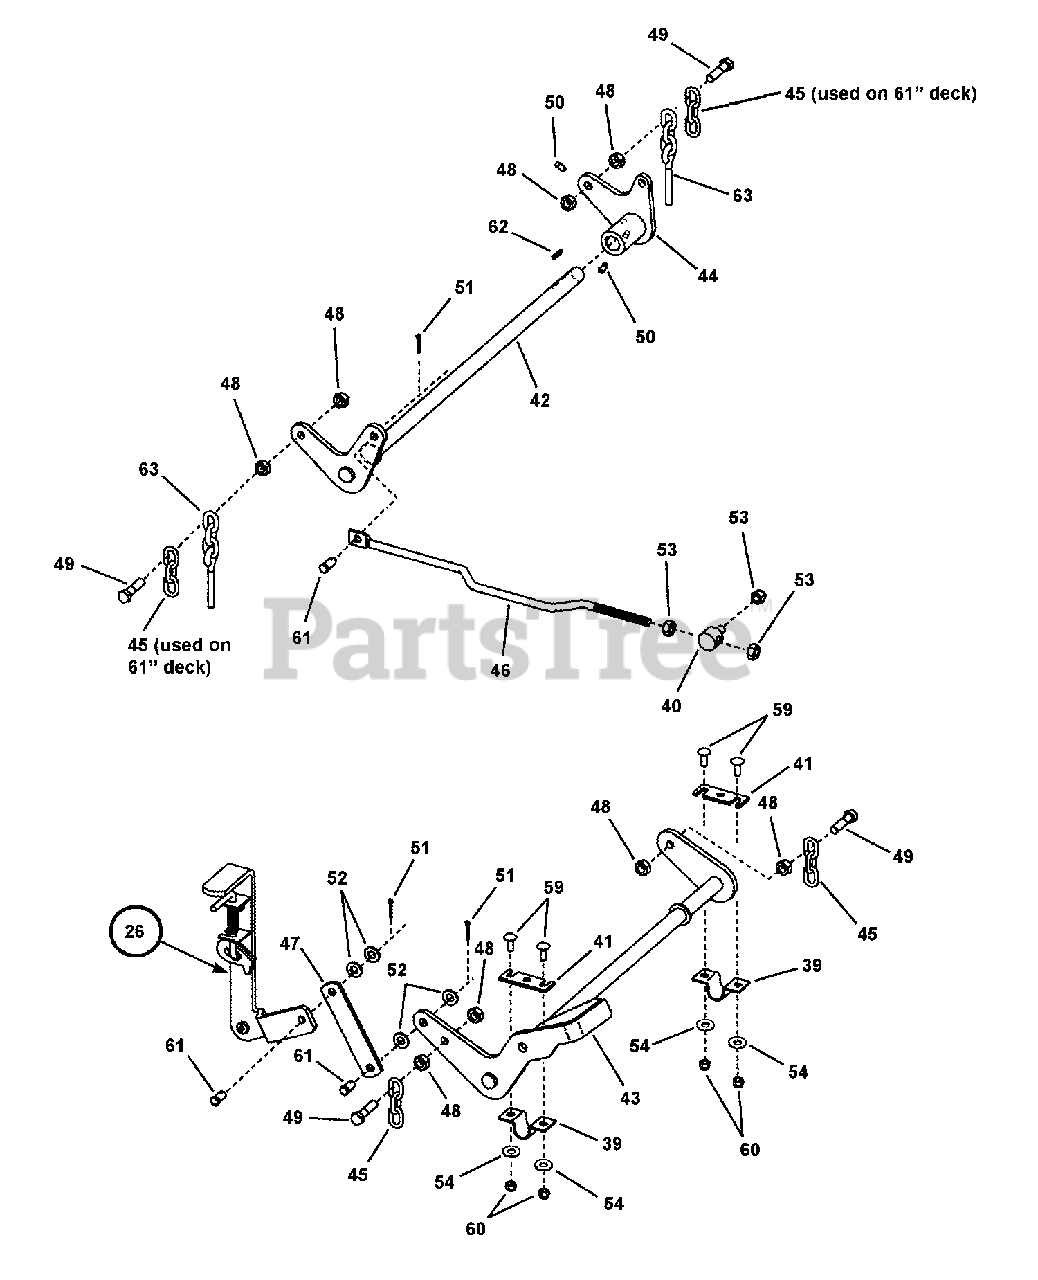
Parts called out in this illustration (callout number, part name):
26	ASSY, Deck Lift Handle
39	BRACKET, Deck Support
40	SWIVEL, Timing Rod (1/2-13 External Thread)
41	SHIM PLATE
42	WELDMENT, Rear Lift
43	WELDMENT, Front Deck Lift
44	WELDMENT, Bellcrank Lift
45	CHAIN, 3 Links
46	ROD, Timing (1/2-13 Thread)
47	LINK, Front
48	NUT, 1/2-13 Hex Flange GR5
49	SCREW, 1/2-13 x 2" Hex Head Cap, GR5
50	SET SCREW, 5/16-18 Square Head Cup Point
51	PIN, 5/32 x 1" Cotter
52	WASHER, .531 I.D. Flat
53	NUT, 1/2-13 HEX SIDE LOCK
54	WASHER, 5/16" Flat
59	BOLT, 5/16-18 x 1" Short Neck Carriage, GR5
60	NUT, 5/16-18 HEX NYLON LOCK
61	PIN, 1/2 x 1-1/8" Clevis
62	KEY, 3/16" Square x 1-1/2"
63	ASSEMBLY, Chain & Eyebolt
